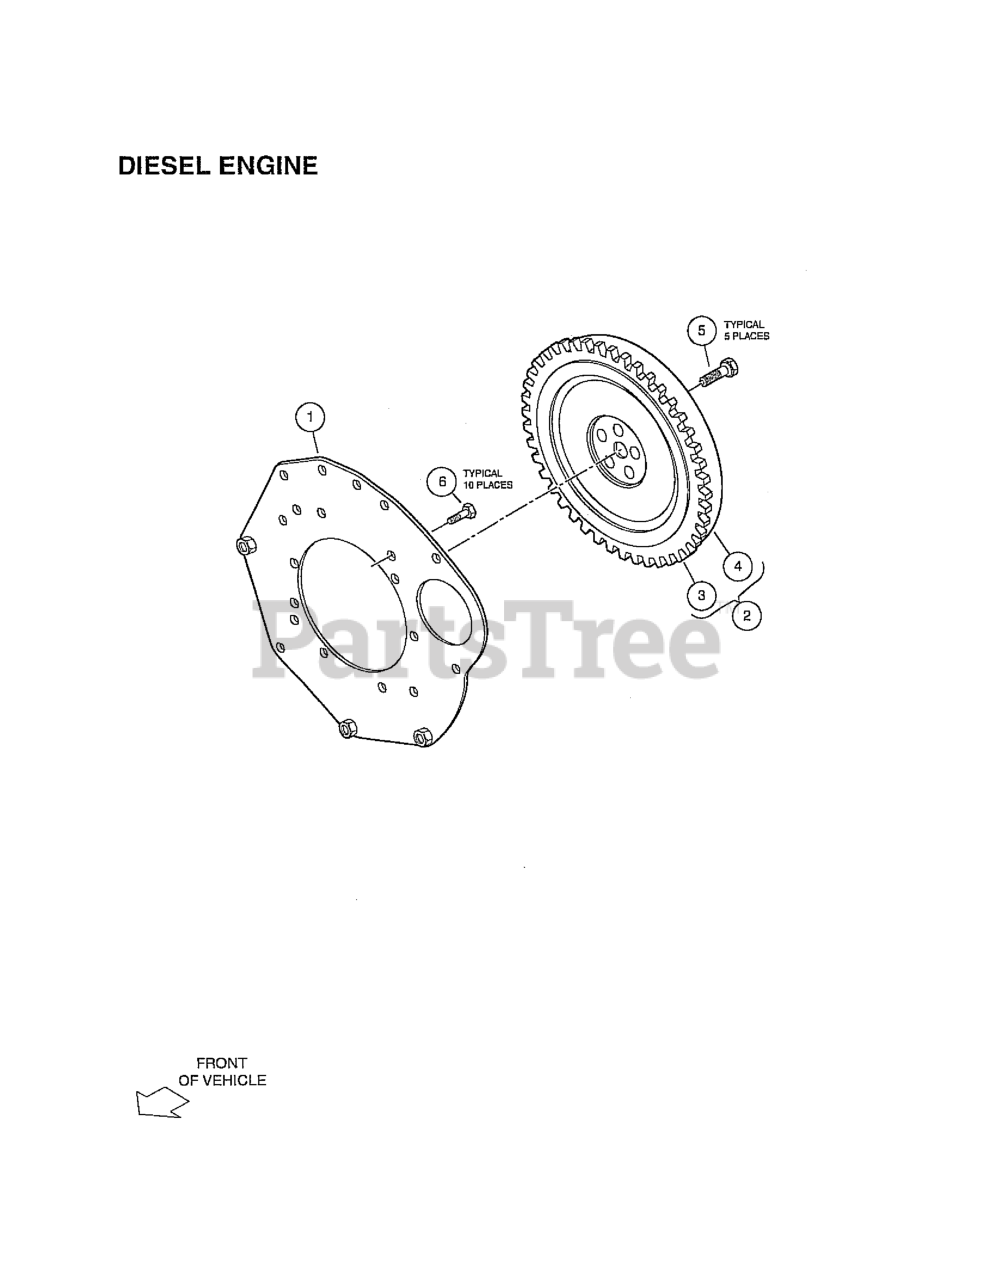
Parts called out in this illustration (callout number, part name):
1	PLATE, REAR END
2	COMP, FLYWHEEL
3	GEAR, RING, D722
5	BOLT, FLANGE, M10 X 1.5 X 25
6	BOLT, END PLATE
